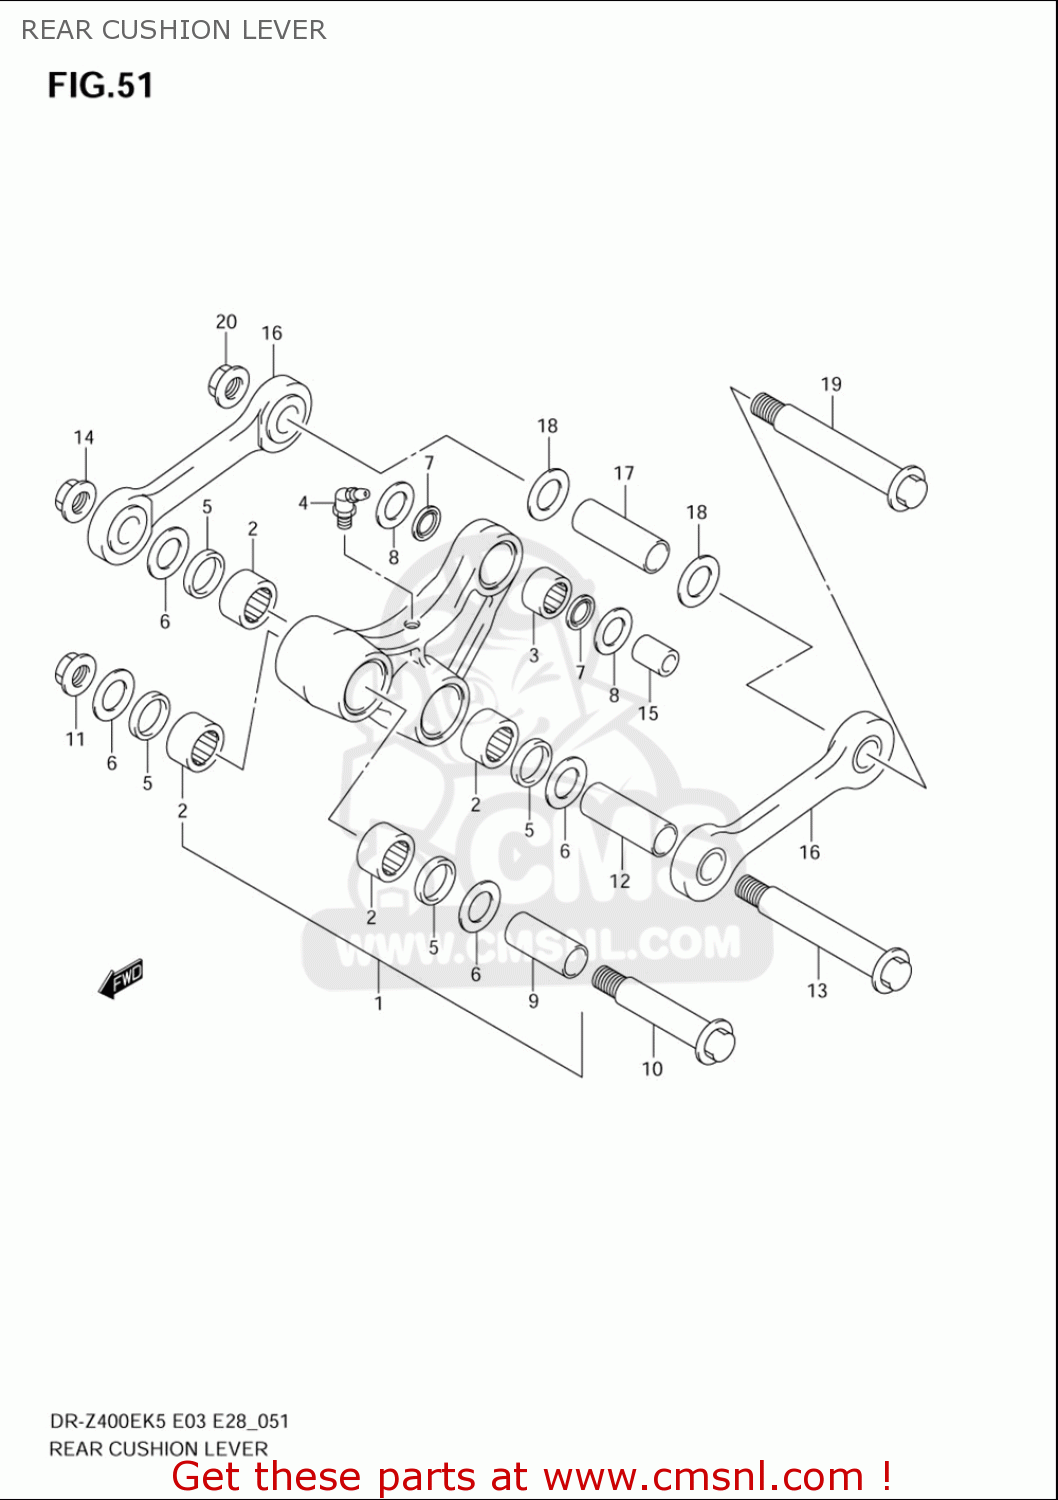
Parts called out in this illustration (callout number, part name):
1	LEVER SET,REAR CUSHION
2	BEARING(20X27X15)
3	BEARING(16X22X12)
4	NIPPLE,GREASE
5	SEAL,CUSHION LEVER DUST
6	WASHER,THRUST SWINGARM RR
7	SEAL,OIL(16X22X2.5)
8	WASHER,THRUST LVR CUSHION RR
9	SPACER,CUSHION LEVER FR
10	BOLT,RR CUSHION LEVER FR
11	NUT
12	SPACER,RR CUSHION
13	BOLT,RR CUSHION
14	NUT
15	SPACER,RR CUSHION LEVER RR
16	ROD SET,RR CUSHION
17	SPACER,RR CUSHION
18	WASHER,THRUST SWINGARM RR
19	BOLT,RR CUSHION
20	NUT
